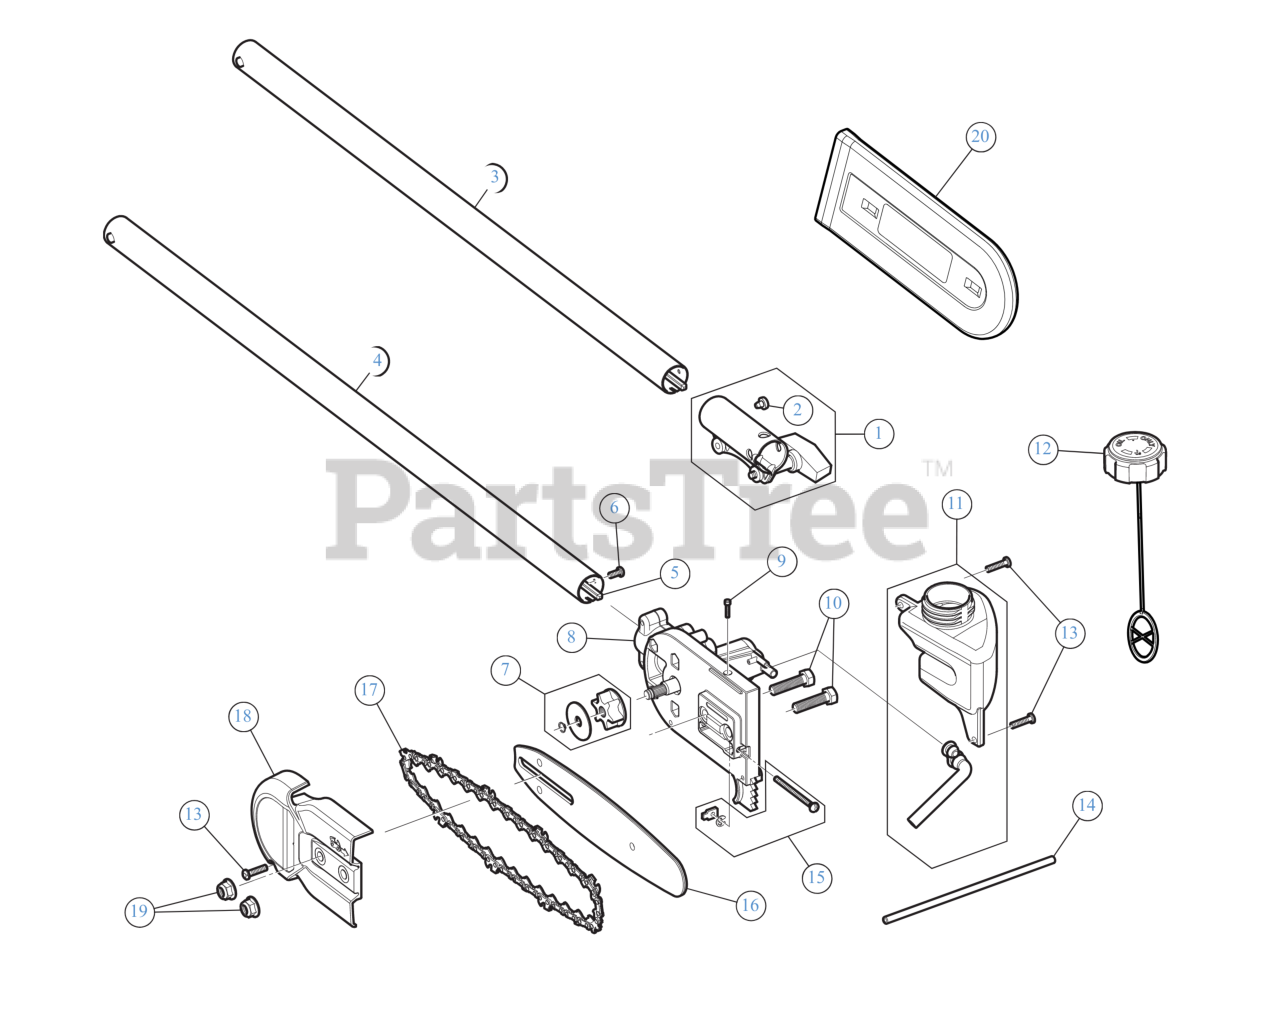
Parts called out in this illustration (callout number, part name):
1	SPLIT BOOM COUPLER KIT
2	SCREW, 10-32X.250 TA
3	EXTENSION BOOM ASSEMBLY
4	LOWER DRIVE SHAFT HOUSING
5	FLEXIBLE DRIVE SHAFT
6	SCREW 1/4-20 X.500
7	SPROCKET ASSEMBLY
8	GEAR BOX ASSEMBLY
9	SCREW 4X40X.50
10	SCREW 5/16-18 x 1.25 GR5
11	OIL TANK ASSEMBLY
12	FUEL CAP ASSEMBLY
13	SCREW, #8-16X.750 PH
14	OIL LINE
15	CHAIN TENSION HDW
16	BAR 8" SPROCKET NOSE
17	CHAIN 8" 34 LINK .043 GAUGE
18	CHAIN GUARD RED
19	FLANGE LOCK NUT 5/16-18
20	8" SCABBARD
